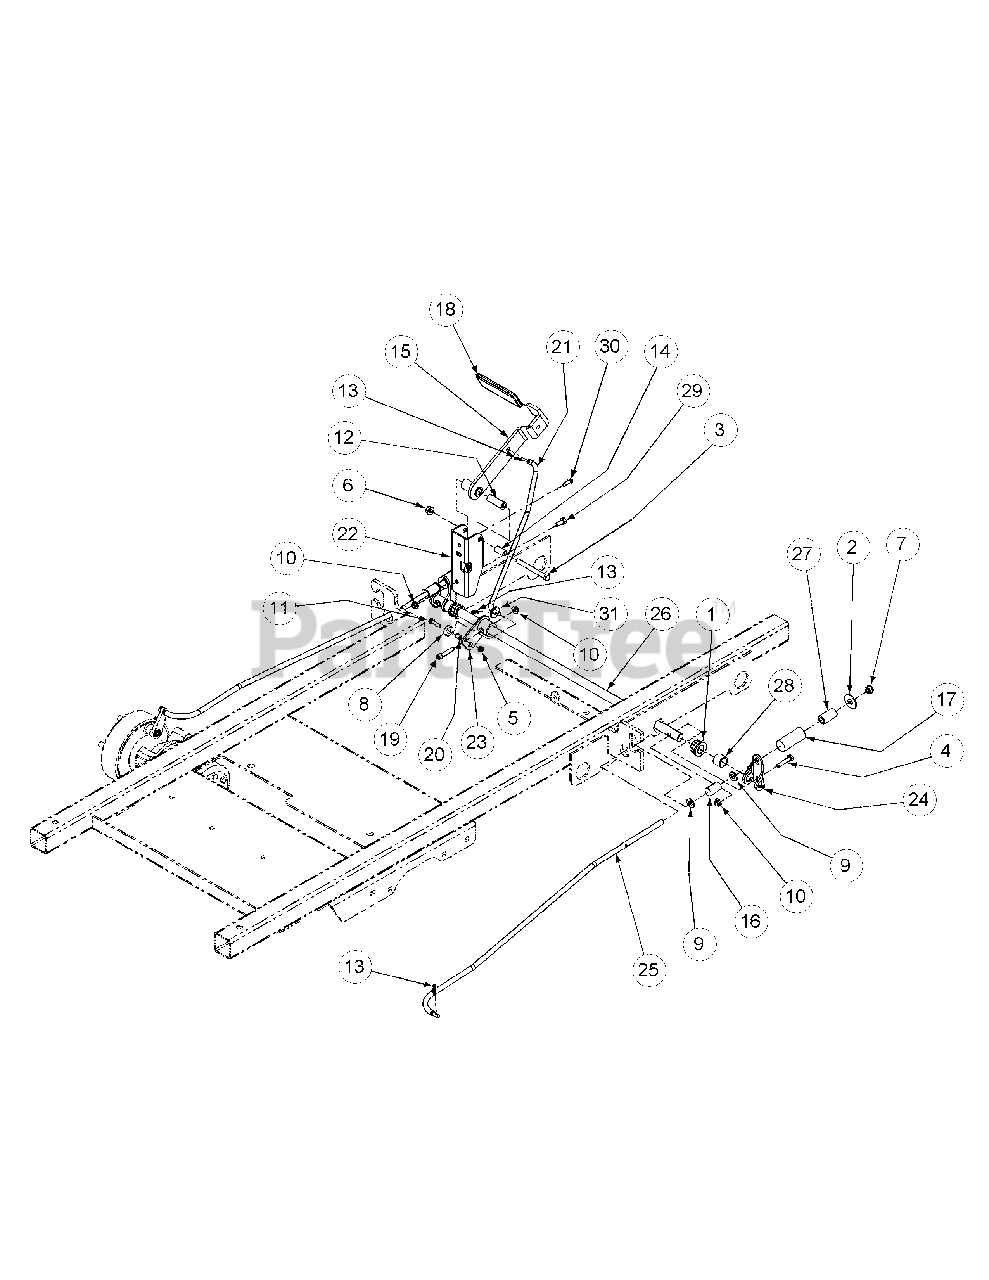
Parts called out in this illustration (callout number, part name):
1	Hex Flange Bearing, .752 ID
2	Flat Washer, 1/2
3	Hex Cap Screw, 3/8-16 x 3-1/4
4	Hex Cap Screw, 5/16-18 x 1-1/2
5	LockNut, 1/4-20, Nylon Insert
6	Flange Lock Hex Nut, 3/8-16
7	Nylock Nut, 7/16-14
8	Spacer, Control Rod
9	Washer, .469 ID x .875 OD x .105
10	Hex Flange Lock Nut, 5/16-18
11	Self Tapping Screw, 1/4-20 x 1.00
12	Spacer, .39 x .63 x 1.75
13	Cotter Pin, .072 x 1.12 Lg
14	Spacer, .375 x .50 x .75 Lg
15	Brake Handle
16	Neutral Brake Spring
17	Force Brake Spring
18	Parking Brake Grip
19	Socket Head CapScrew, 5/16-18 x 1.50
20	Spacer, .375 OD x .257 ID x .438
21	Brake Rod
22	Parking Brake Mounting Bracket
23	Brake Arm Assembly
24	Brake Bracket
25	Linkage Brake Rod
26	Pivot Brake Shaft
27	Low Pressure Hose
28	Spacer, .76 ID x 1.0 OD x .75
29	HHCS, 5/16-18 x 1.0
30	Screw, TT, 1/4-20, 0.75, Hex Index Washer
31	Flat Washer, .406 ID, 1.0 OD, .105
